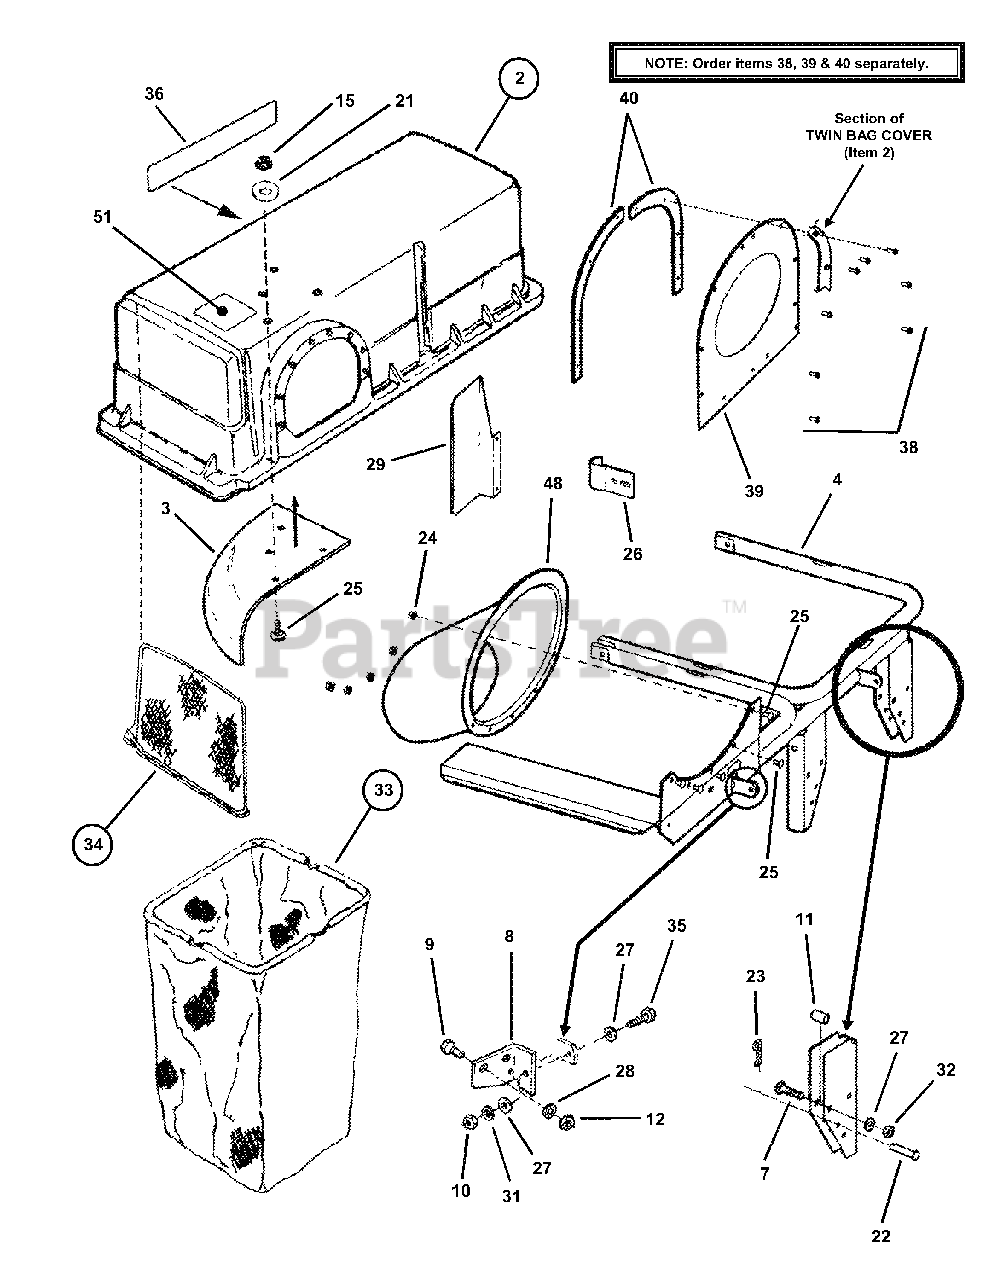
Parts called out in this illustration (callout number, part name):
2	COVER, Twin Bag
3	SECTOR
4	WELDMENT, Frame
7	BOLT, 5/16-18 x 1-1/2" Carr.
8	HINGE, Top
9	SCREW, 1/4-28 x 3/4" Cap
10	NUT, 5/16-24 Hex Center Lock
11	PAD, Bumper Mount
12	NUT, 1/4-28 Hex
15	NUT, 1/4-20 Hex
21	WASHER, 1/4" Flat
22	PIN, 5/16 x 11/16" Clevis
23	PIN, 3/32 x 1-1/2" Hair
24	NUT, 1/4-20 Flange Lock
25	BOLT, 1/4-20 x 1/2" Carriage
26	SUPPORT, Bumper
27	WASHER, 5/16" Flat
28	WASHER, 1/4 Int.Tooth Lock
29	GUARD, Muffler
31	WASHER, 5/16 Split Lock
32	NUT, 5/16-18 Hex Center Lock
33	ASS'Y,Bag
34	ASS'Y, Screen (Indented Items)
35	SCREW, 5/16-24 x 1" Cap
36	DECAL, Snapper
38	SCREW, #10-24 x 1/2" S. Tap
39	SEAL
48	INLET, Twin Bagger
51	DECAL, Chute/Deflector
